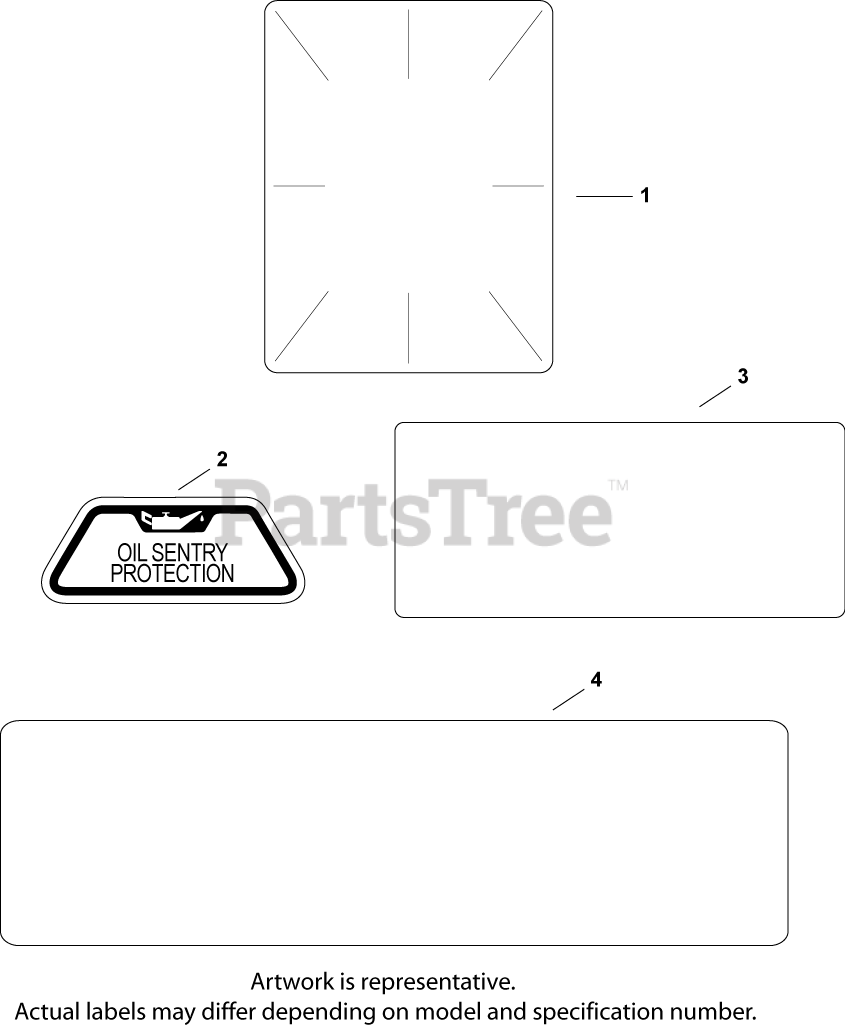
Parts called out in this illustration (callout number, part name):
1	DECAL, CLEAR LAMINATE USE 25 113 70-S
2	DECAL, OIL SENTRY - (#DSC)
3	DECAL, REPL ENGINE(NONCERT)
4	DECAL, 20 HP - DISCONTINUED
